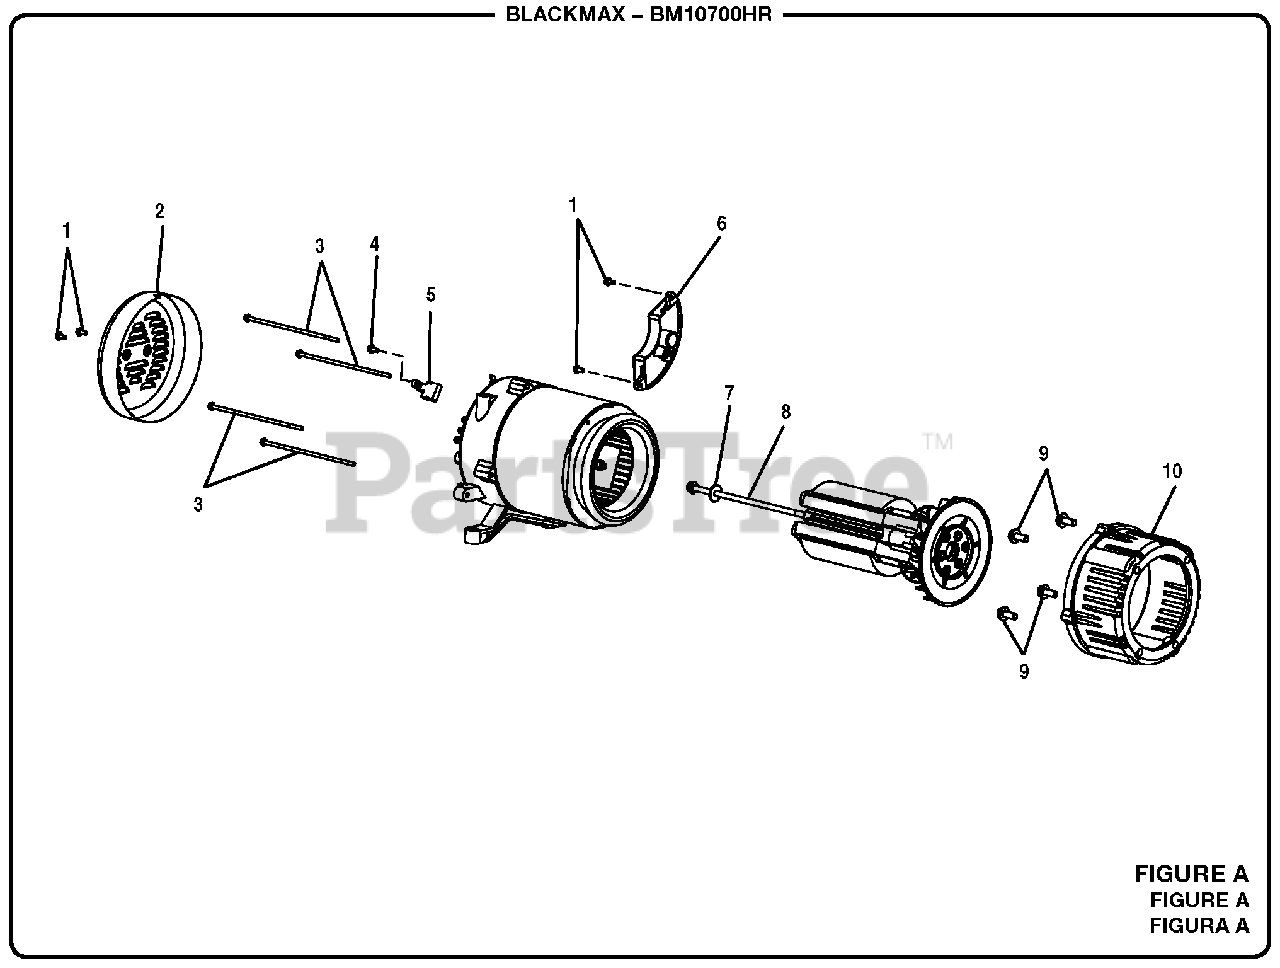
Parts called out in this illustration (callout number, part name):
2	Brush Cover
3	Bolt (1/4-20 x 6 in)
4	Bolt (Brush Assembly)
5	Brush Assembly
6	Automatic Voltage Regulator
7	Lock Washer (5/16 in)
8	Bolt (5/16-24 x 9-1/2 in,Hex Hd)
9	Bolt (3/8-18 x 1-1/4 in)
10	Engine Adapter
